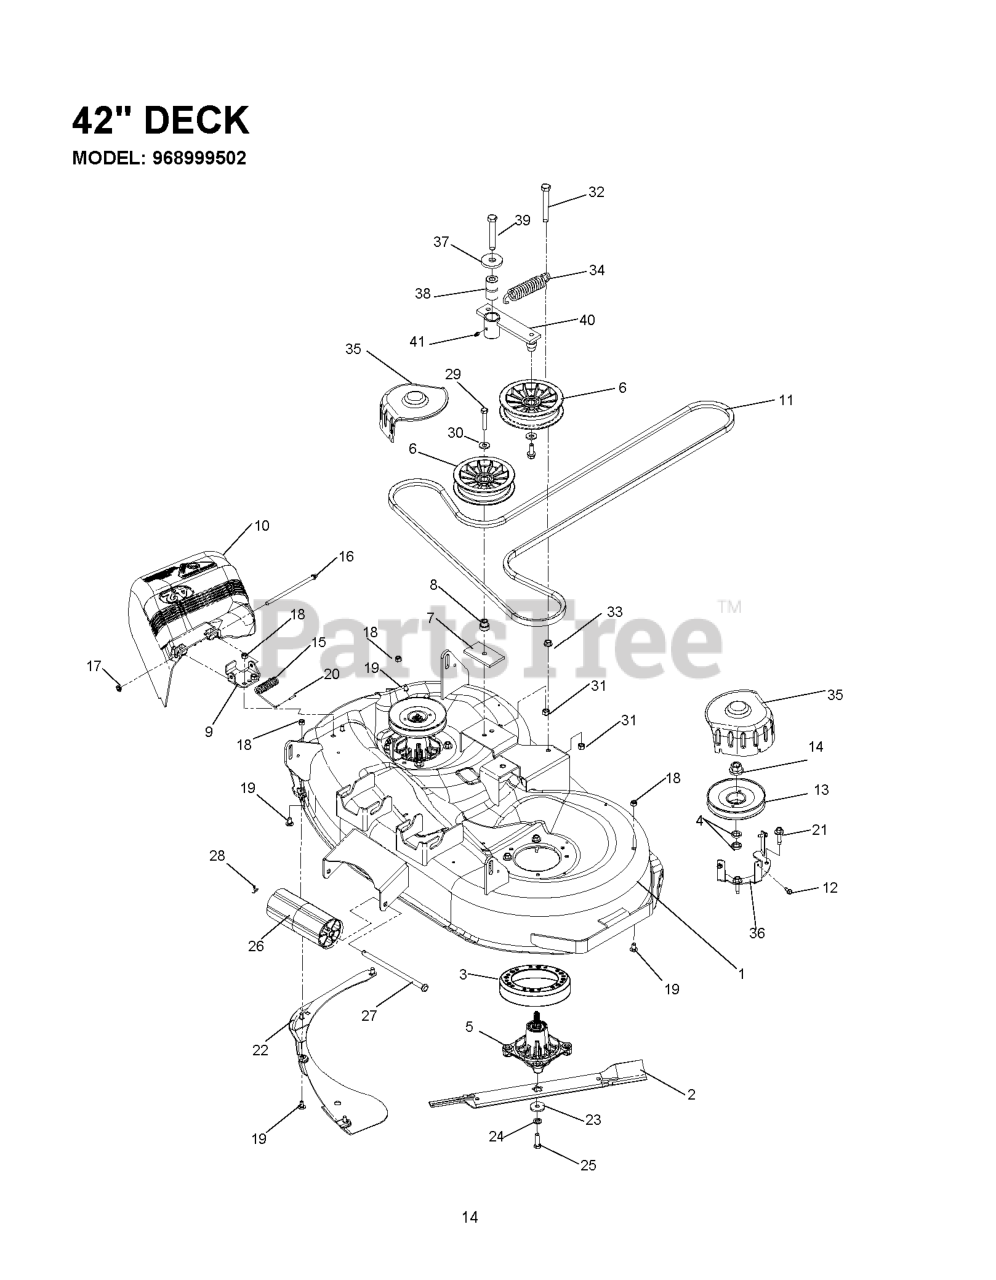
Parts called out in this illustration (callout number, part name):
1	DECK W/DECAL 42" ORANGE
2	BLADE 42" MULCHING STD
3	STRIPPER-ROUND-UNIVERSAL
4	WASHER-SPACER
5	CUTTER HOUSING
6	IDLER
7	SUPPORT PLATE
8	IDLER BUSHING
9	BRKT.DEFLECTOR.38"2005+
10	DEFLECTOR 42
11	BELT, DECK
12	SCREW 1/4 X 5/8
13	RP.PULLEY, DECK
14	LOCKNUT - 9/16
15	SPRING, TORSION DEFLECTOR
16	ROD, HINGE
17	PUSH NUT
18	NUT 5/16 NYLOC
19	CARRIAGE BOLT 5/16C X 5/8"
20	CAP-SLEEVE
21	WASHER HEAD SCREW
22	BAFFLE VORTEX 42
23	WASHER, HARDENED
24	WASHER, LOCK HVY HLCL 3/8
25	BOLT, HEX 3/8-24 X 1.25 GR 8
26	NOSE ROLLER-48"
27	NOSE ROLLER ROD
28	RP_COTTER PIN 1/8 X 3/4
29	HCS 3/8C X 2
30	WASHER 3/8 FLAT
31	NUT 3/8-16 NYLOC
32	HCS 3/8C X 2 1/2
33	NUT 3/8C WHIZ
35	SPINDLE COVER
36	MOUNT, BELTSHIELD
37	WASHER, SUPPORT
38	PIVOT BUSHING
39	HCS 1/2C X 3 1/4
41	ZERK
